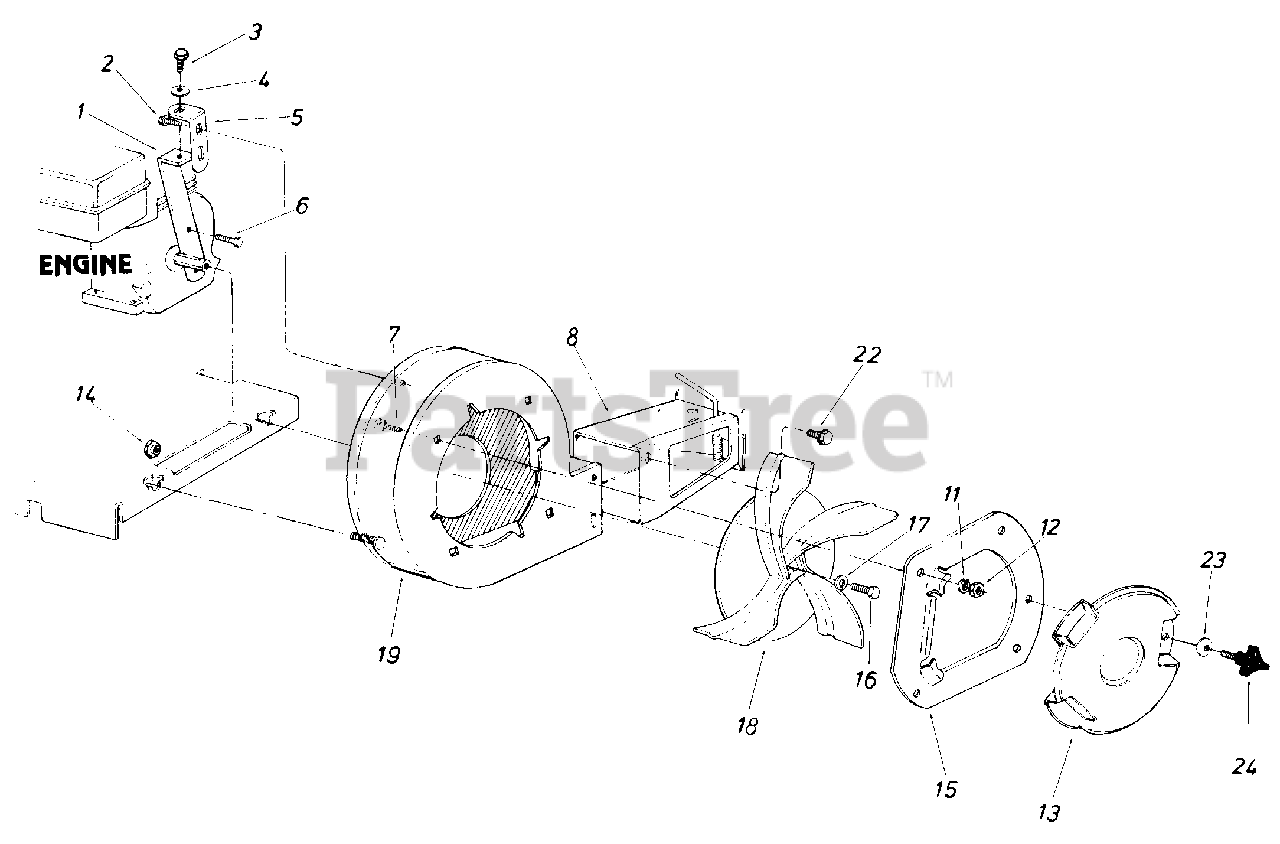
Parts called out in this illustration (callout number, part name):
3	Hex Bolt 5/16-18 x .75" Lg.*
4	L.-Wash. 5/16" I.D.*
7	Carriage Bolt 5/16-18 x .62" Lg.*
12	Hex Nut 5/16-18 Thd.*
13	Blower Guard
14	Hex Shoulder Nut.50" I.D.
15	Nozzle Plate Ass'y.
16	Hex Bolt 3/8-24 x 1.25" Lg.*
17	L.-Wash. 3/8" I.D. HD.
18	Air Vane Plate Ass'y.
19	Blower Housing Ass'y. - Comp.
22	Hex Sems Bolt 5/16-18 x .62" Lg.*
23	Belleville Wash. 34 " I.D. x .87 "O.D.
24	3-Arm Thumb Scr. 5/16-18 x .75" Lg.
